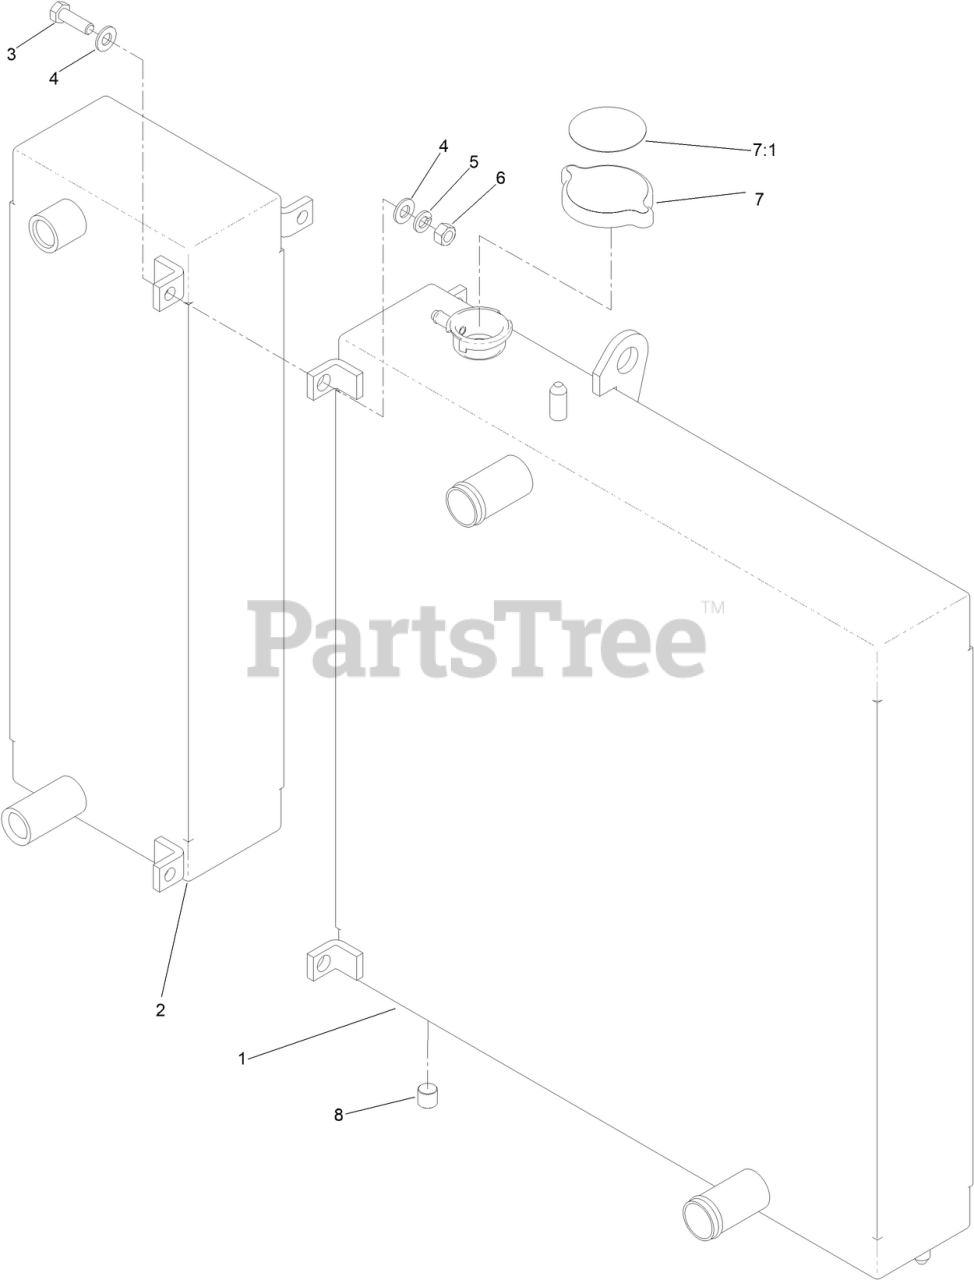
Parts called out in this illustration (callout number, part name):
1	RADIATOR
2	OIL COOLER
3	SCREW-HH
4	WASHER-PLAIN
5	WASHER-LOCK
6	NUT-HEX
7	CAP-RADIATOR
7:1	DECAL-DANGER
8	PLUG-PIPE
